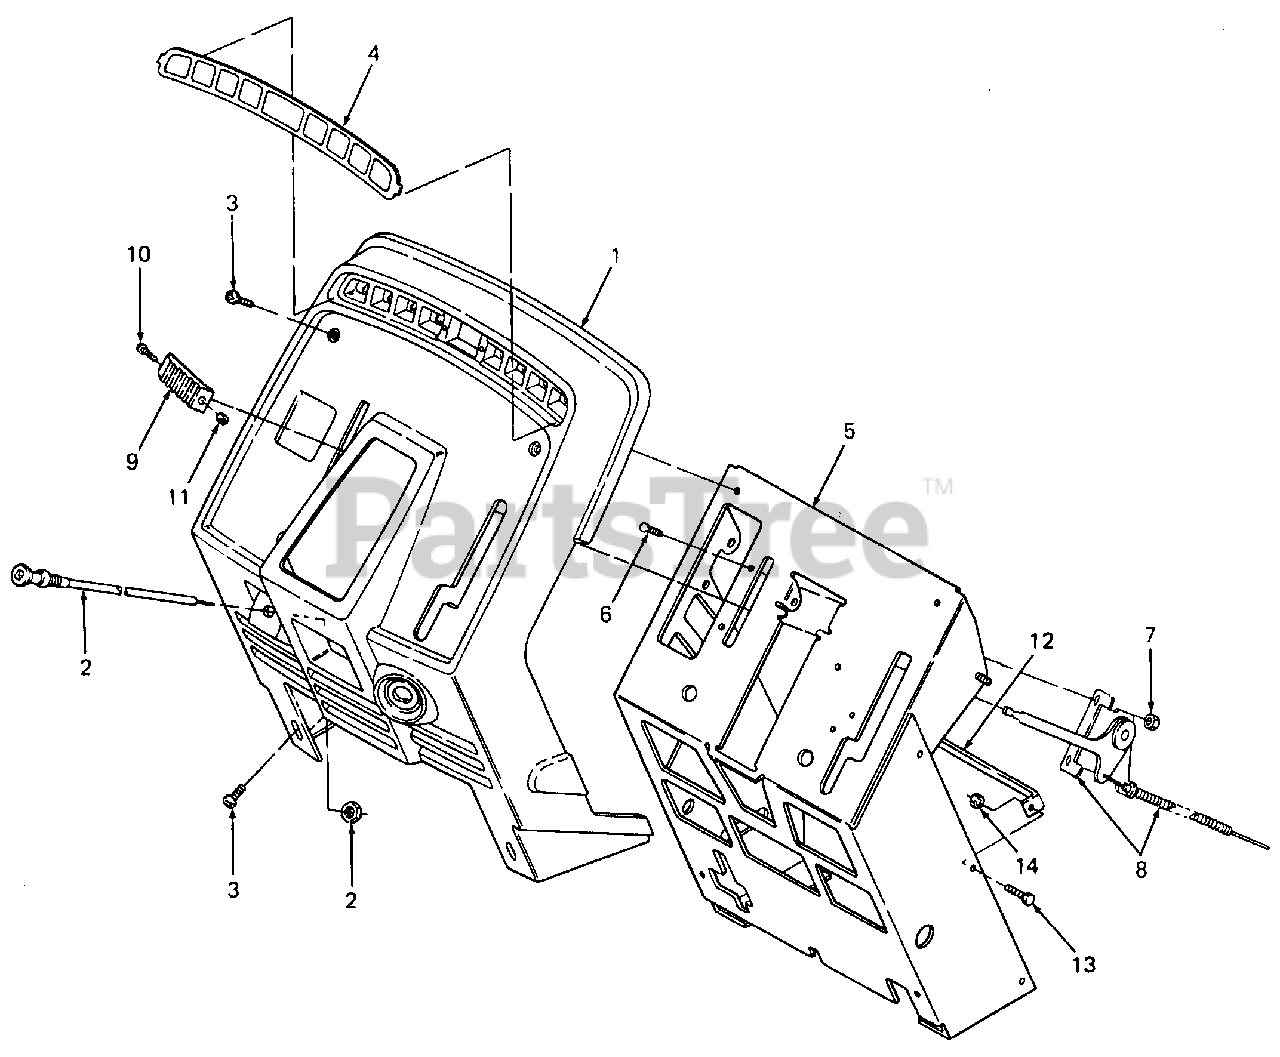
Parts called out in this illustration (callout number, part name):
1	Panel, Instrument
2	Choke Cable w/Nut
3	Screw, Pan Hd Cutting, #10-24 X .75 Lg
4	Label, Dash
7	Nut, Hex Keps, #10-32
8	Control, Throttle
9	Knob, Throttle
10	Screw, Cross Rec Truss Hd, #8-32 X .38 Lg
11	Nut, 8-32
12	Bracket, Harness
13	Screw, Hex Cap, 1/4-20 X .50 Lg GR5
14	Nut, Hex Patch Lock, 1/4-20
